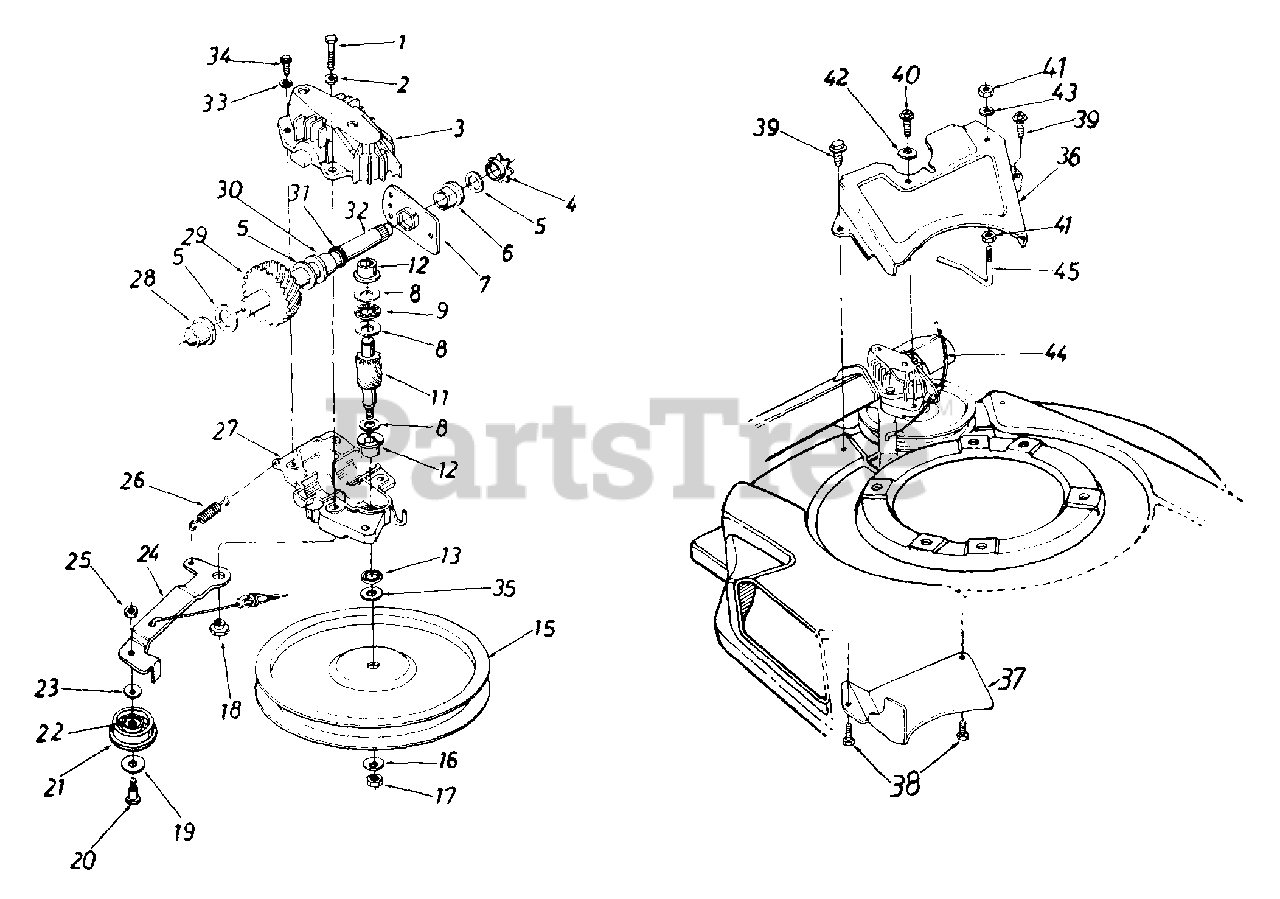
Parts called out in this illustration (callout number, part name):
1	Hex Bolt 1/4-20 x 1.25" Lg. w/Patch
2	L-Wash. 1/4" I.D.
3	Upper Hsg. Half
4	#48 Sprocket 7 Tooth x 1/2 Pitch
5	Fl-Wash. 5/8" I.D. x .030
6	Hex Flange Brg..631" I.D.
8	Thrust Wash..382" I.D. x .70" O.D.
9	Thrust Bearing .375" I.D. x .812" O.D.
11	11 Tooth Helical Gear
12	Flange Bearing
13	Oil Seal
15	Fl-Pulley 5.06" I.D.
16	Bell-Wash..265" I.D. x.75"
17	Hex Nut 1/4-28 L.H. Thd.
18	Shld. Spacer .375" Dia. x .170
19	Fl-Wash..390" I.D. x 1.0"
20	Shld. Bolt .375" Dia. x .40"
21	Fl-Idler Plastic 1.50" Dia.
22	Needle Brg..375" x .375"
23	Bell-Wash..265" I.D. x .75"
24	Idler Brk't. Ass'y.
25	Hex Patch L-Nut 1/4-28 Thd.
26	Extension Spring 1.12" Lg.
27	Lower Hsg. Half
28	Flange Bearing .56" Dia.
29	33 Tooth Helical Gear
30	Flange Bearing .629" Dia.
31	Oil Seal .625" Dia.
32	Gear Sprocket Shaft
33	L-Wash. #10 I.D.
34	Hex B-Tap Scr. #10 x .62"
35	Hex Washer .26" x .88"
39	Hex AB-Tap Scr. 1/4 x .50" Lg.
40	Hex B-Tap Scr. 1/4 x .62" Lg.
41	Hex Nut 1/4-20 Thd.
42	Bell-Wash..265" I.D. x .75"
43	L-Wash. 1/4" I.D.
44	S.P. Cable - 48" Lg.
45	S.P. Belt Guards
